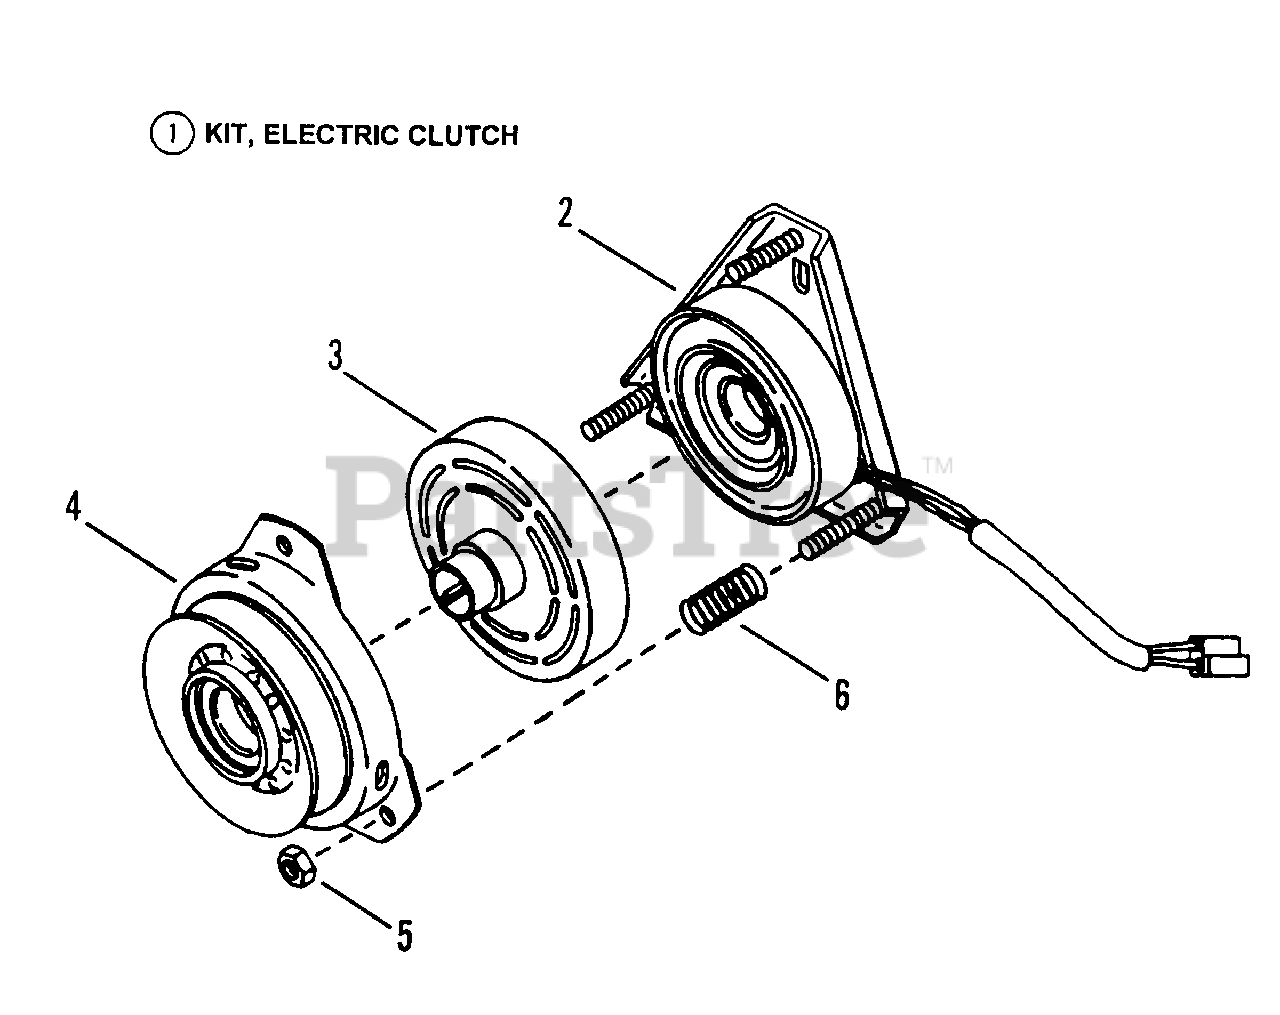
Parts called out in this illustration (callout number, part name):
1	KIT, Electric Clutch
2	FIELD COIL
3	ROTOR
4	ASSEMBLY, Arm Pulley
5	NUT, 3/8-24 Hex Lock
6	SPRING, Coil
